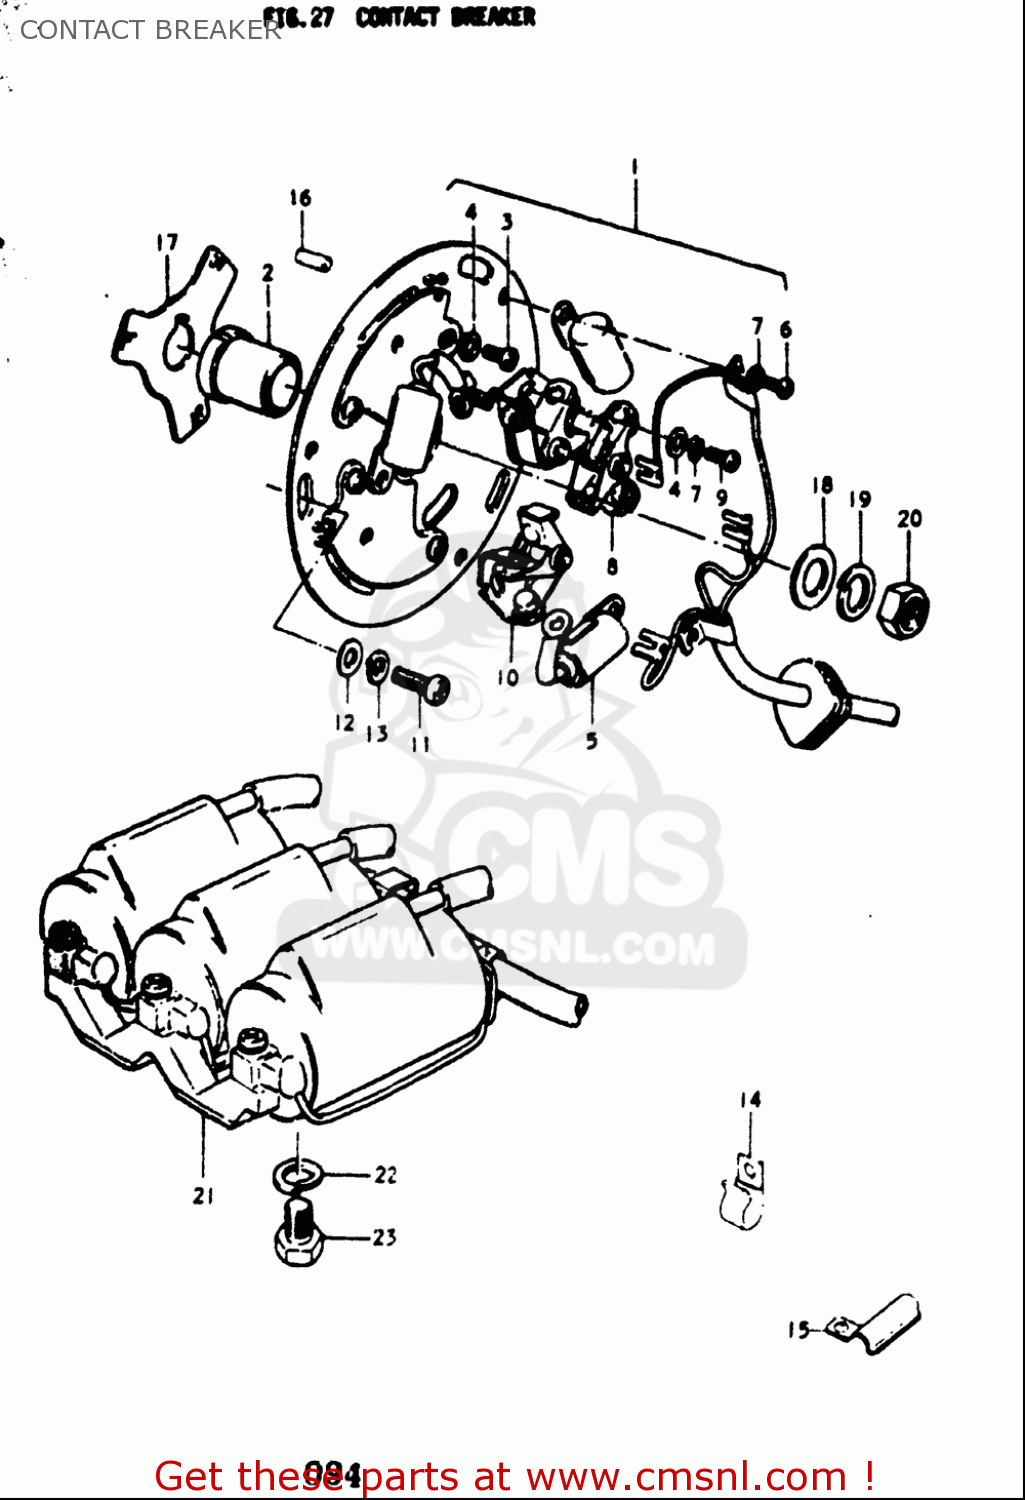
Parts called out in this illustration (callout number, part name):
2	CAM,CONTACT BREAKER
3	SCREW 4X6
4	WASHER
5	CONDENSER
6	SCREW
7	WASHER,LOCK
8	POINT ASSY
9	SCREW 4X6
10	POINT ASSY
11	SCREW(5X12)
12	WASHER
13	WASHER,LOCK
14	CLAMP
16	PIN
18	WASHER
19	WASHER,LOCK
20	NUT
22	WASHER,LOCK
23	BOLT
